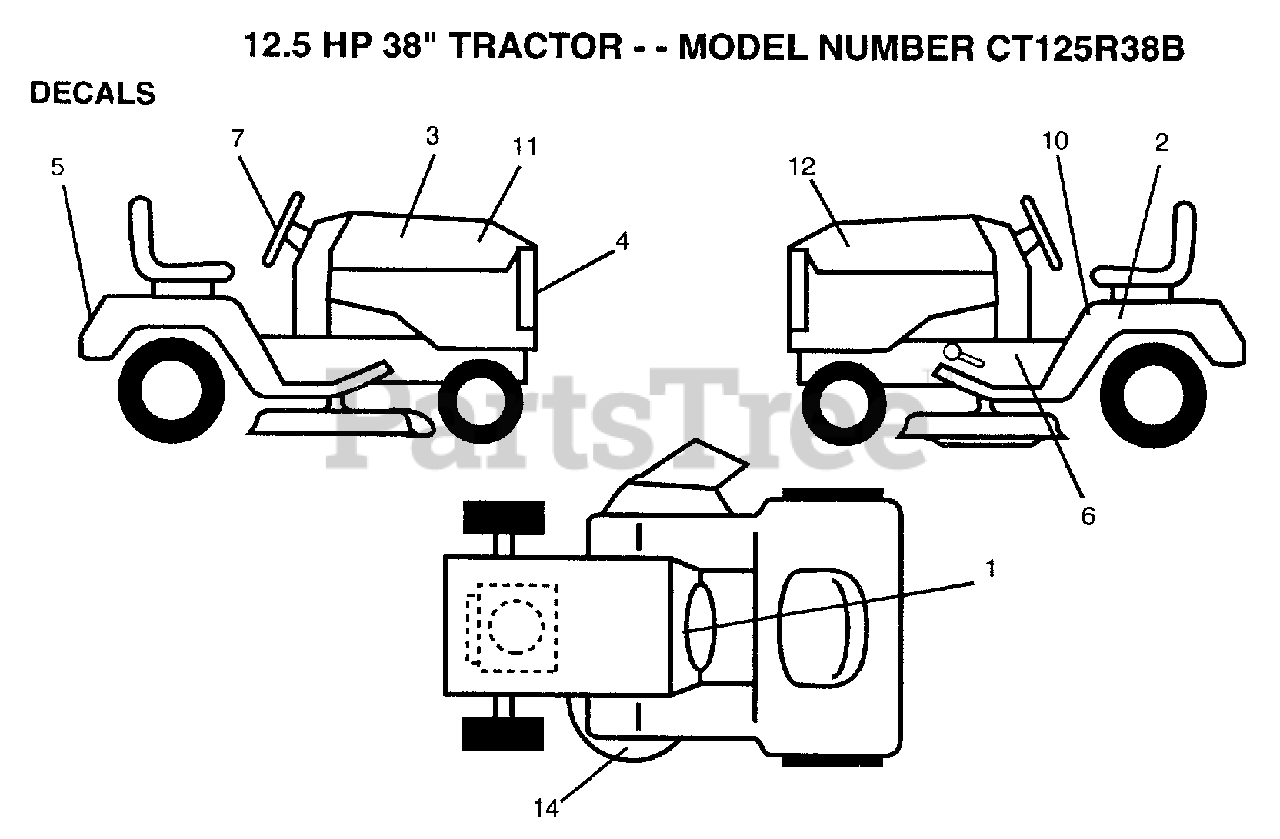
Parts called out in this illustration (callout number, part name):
1	DECAL INST ENGINE
2	DECAL.FEND.QUICKS
3	DECAL.HOOD.12.5
4	DECAL.GRILLE
5	DECAL.FENDER
6	IND HGT DECK DECA
7	DECAL.STG.WHL.INS
10	DECAL
11	DECAL.HOOD.RH
12	DECAL.HOOD.LH
